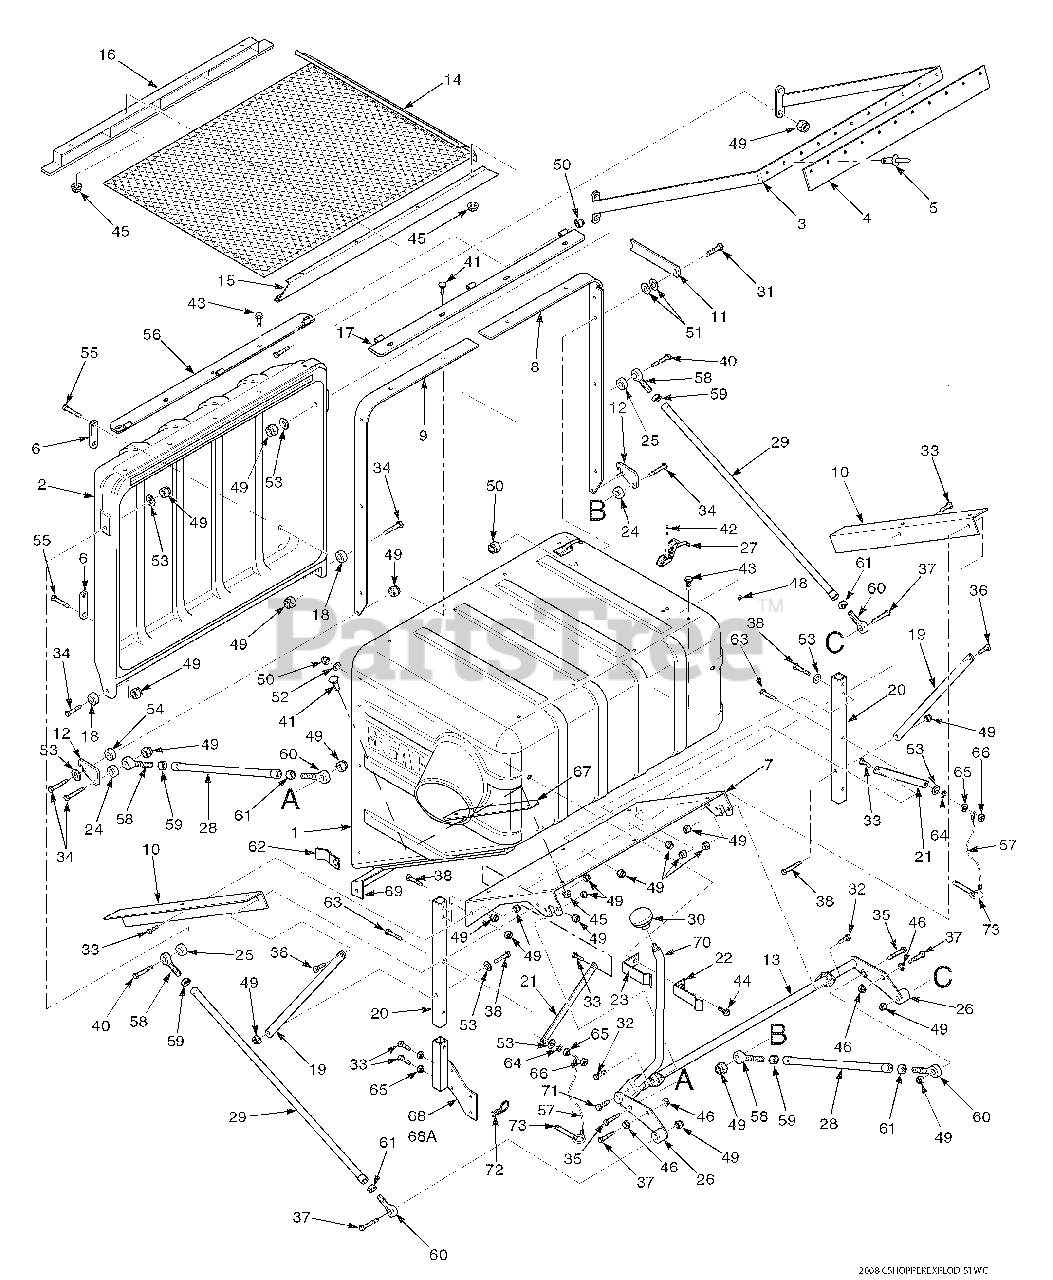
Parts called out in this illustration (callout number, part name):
1	Hopper, GC-STC-CS
2	Door, GC-CS
3	Sweeper Weldment, GC-CS
4	Pad, Rubber
5	Pop Rivet, 3/16 x .652
6	Plate, Stiffener
7	Support Frame, Hopper
8	Hinge Bracket, LH
9	Hinge Bracket, RH
10	Bracket, Hopper Support
11	Latch, Door Prop
12	Plate, Latch
13	Bellcrank Weldment, Upper
14	Debris Screen Weldment
15	Screen Support Weldment, Rear
16	Screen Support Weldment, Front
17	Hinge Weldment, Hopper
18	Spacer
19	Brace Stiffener, Short
20	Tube, Upright
21	Brace, Engine Mount
22	Latch, Dump Rod Inner
23	Latch, Dump Rod Outer
24	Spacer
25	Spacer
26	Spacer
27	Latch, Hood
28	Linkage Assembly, Lower
29	Linkage Assembly, Upper
31	Bolt, Hex Head 5/16-18 x 1-1/4"
32	Bolt, Hex Head 3/8-16 x 3/4"
33	Bolt, Hex Head 3/8-16 x 1"
34	Bolt, Hex Head 3/8-16 x 1-1/2"
35	Bolt, Hex Head 3/8-16 x 1-3/4"
36	Bolt, Hex Head 3/8-16 x 1-1/4"
37	Bolt, Hex Head 3/8-16 x 2"
38	Bolt, Hex Head 3/8-16 x 2-1/4"
39	Bolt, Hex Head 5/16-18 x 3-1/2"
40	Bolt, Hex Head 3/8-16 x 3-1/2"
41	Bolt, Carriage 5/16-18 x 1"
42	Screw, #10-32 x 1/2"
43	Cap Screw, 5/16-18 x 3/4" Serr. Flan.
44	Cap Screw, 5/16-18 x 1" Serr. Flan.
45	Nut, 5/16-18 Serrated Flange
46	Nut, 3/8-16 Serrated Flange
47	Nut, 3/8-16 UNC Jam
48	Nut, #10-32 Elastic Stop
49	Nut, 3/8-16 Elastic Stop
50	Nut, 5/16-18 Elastic Stop
51	Washer, Special Wave
52	Washer, 5/16-.375 x .875 x .083 Flat
53	Washer, 3/8-.931 x .938 x .105 Flat
54	Bushing, Hopper Latch GC-CS
55	Bolt, Hex Head 3/8-16 x 3"
56	Hinge Weldment, Door
57	Lanyard
58	Rod End Male, 3/8-24 LH Thread
59	Nut, 3/8-24 UNF L.H. Thread
60	Rod End Male, 3/8-24 RH Thread
61	Nut, 3/8-24 UNF R.H. Thread
62	Alignment Bracket, GC-CS
63	Bolt, Hex Head 3/8-16 x 2-1/2"
64	Lock Wasker, 3/8-16 Spring
65	Nut, 3/8-16 UNC Zinc
66	Nut, 3/8-16 Center Lock
67	Retainer Strip, Hopper
68	Mounting Bracket Weldment, RH
68A	Mounting Bracket Weldment, LH
69	Bracket, Lower Stiffener
70	Rod, Dump Lever
71	Bolt, Hex Head 5/16-18 x 1-3/4"
72	Hair Pin, Cotter
73	Pin, Ring 1/2" x 2-1/4"
